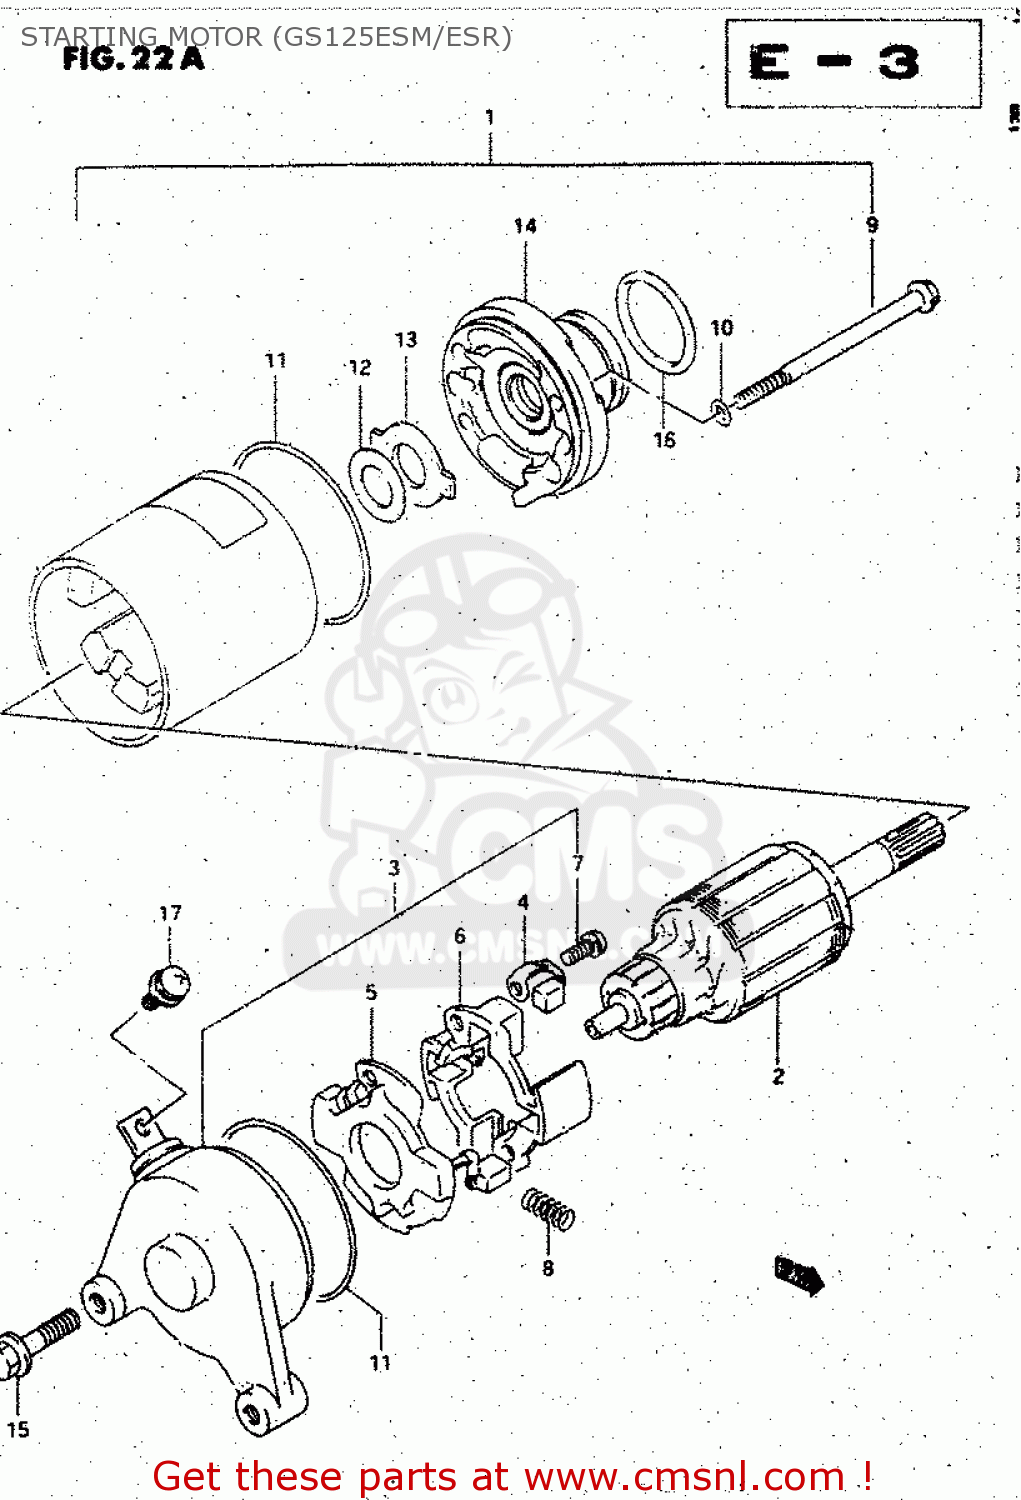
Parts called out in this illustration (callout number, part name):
1	MOTOR ASSEMBLY,STARTING
2	ARMATURE
3	FRAME ASSEMBLY,COMMUTATOR
4	BRUSH
5	BRUSH SUB ASSY,STARTER
6	HOLDER,BRUSH
7	SCREW
8	SPRING
9	BOLT
10	O RING
11	O RING
12	SHIM
13	PLATE,LOCK
14	BRACKET
15	BOLT
16	O RING(D:3,ID:24.5)
17	SCREW(5X8)
